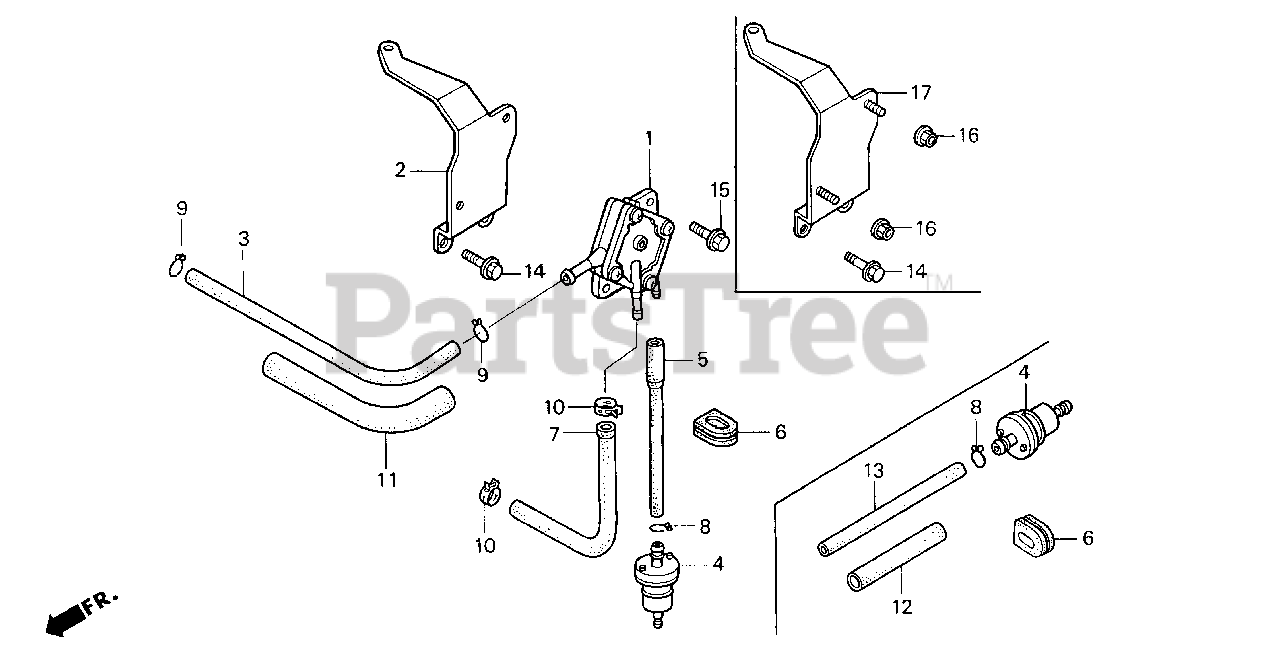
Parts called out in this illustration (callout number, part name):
1	PUMP ASSY., FUEL
2	STAY, FUEL PUMP *R8* (BRIGHT RED)
3	TUBE, FUEL
4	FILTER, FUEL
5	TUBE B, FUEL
6	GROMMET, WIRE
7	BULK HOSE, FUEL (5.5X8000) (5.5X205)
8	CLIP, TUBE (B8)
9	CLIP, TUBE (B10)
10	CLIP, TUBE (10.5MM)
11	BULK HOSE, VINYL (11X13X3000) (11X13X160)
14	BOLT, FLANGE (6X8)
15	BOLT, FLANGE (6X14)
16	NUT, FLANGE (6MM)
17	STAY, FUEL PUMP *R8* (BRIGHT RED)
